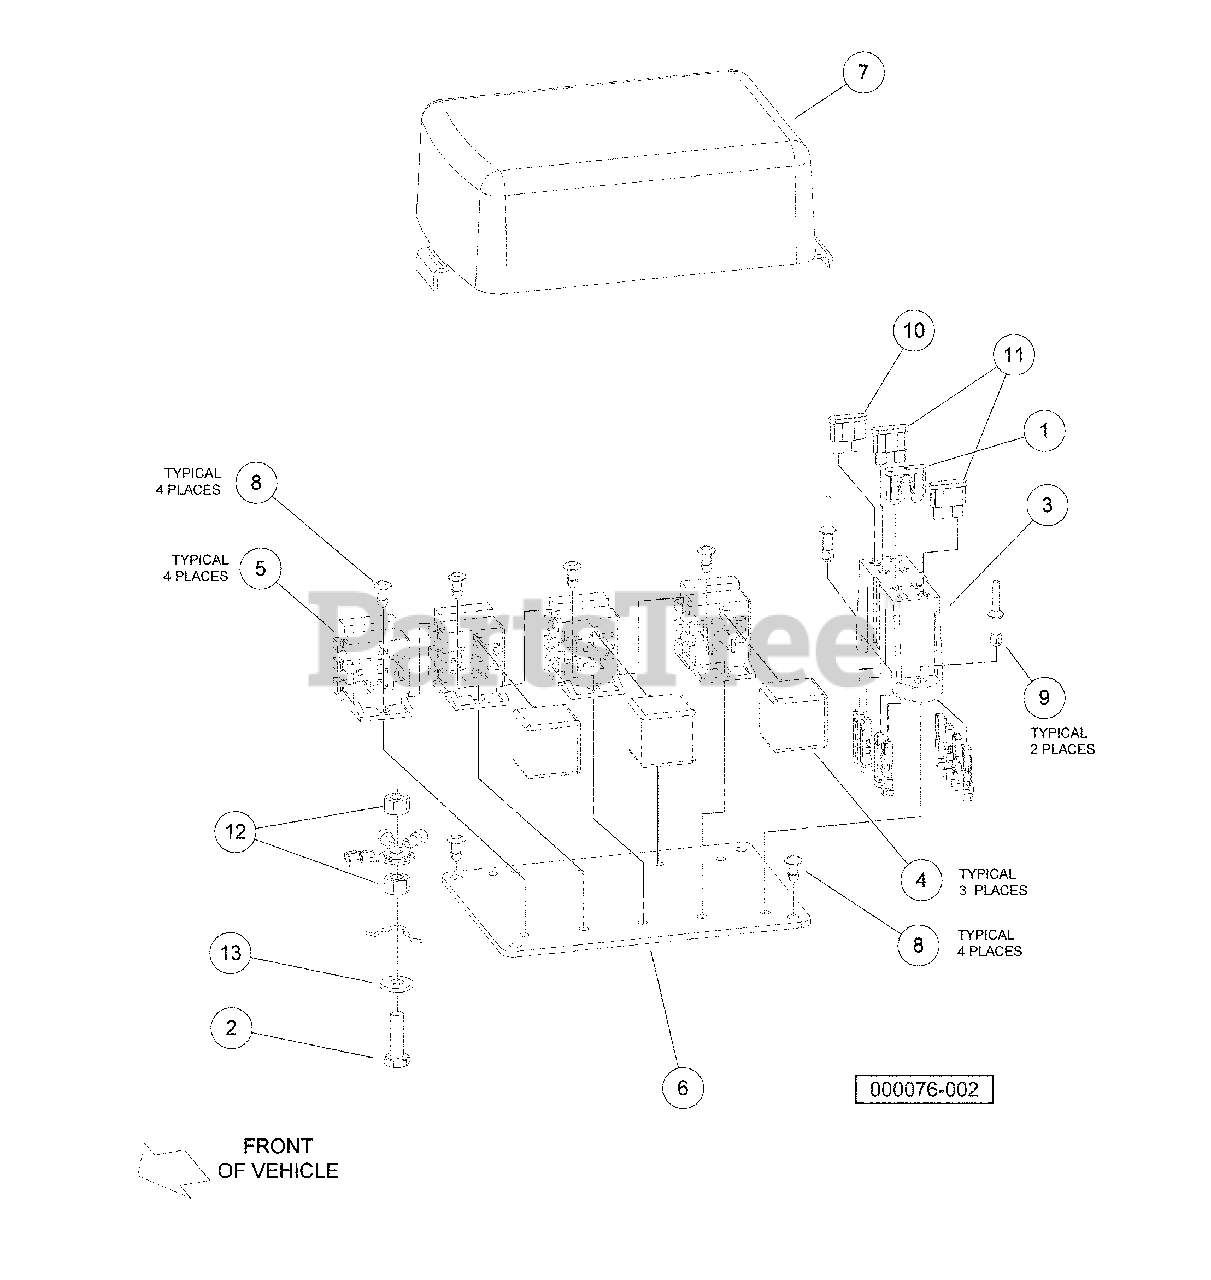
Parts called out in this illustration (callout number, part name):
1	Fuse, 10-Amp
2	Screw, 1/4-20 X .88 Hex Hd Cap
3	Fuse Block
4	Relay, Mini ISO, SPDT
5	Connector, Relay
6	Plate, Electrical
7	Cover, Electrical
8	Fastener, Push-in
9	Rivet, Drive
10	Fuse, 25-Amp
11	Fuse, 30-Amp
12	Locknut, 1/4-20 Dimpled
13	Washer, 1/4 Type A Narrow Flat
